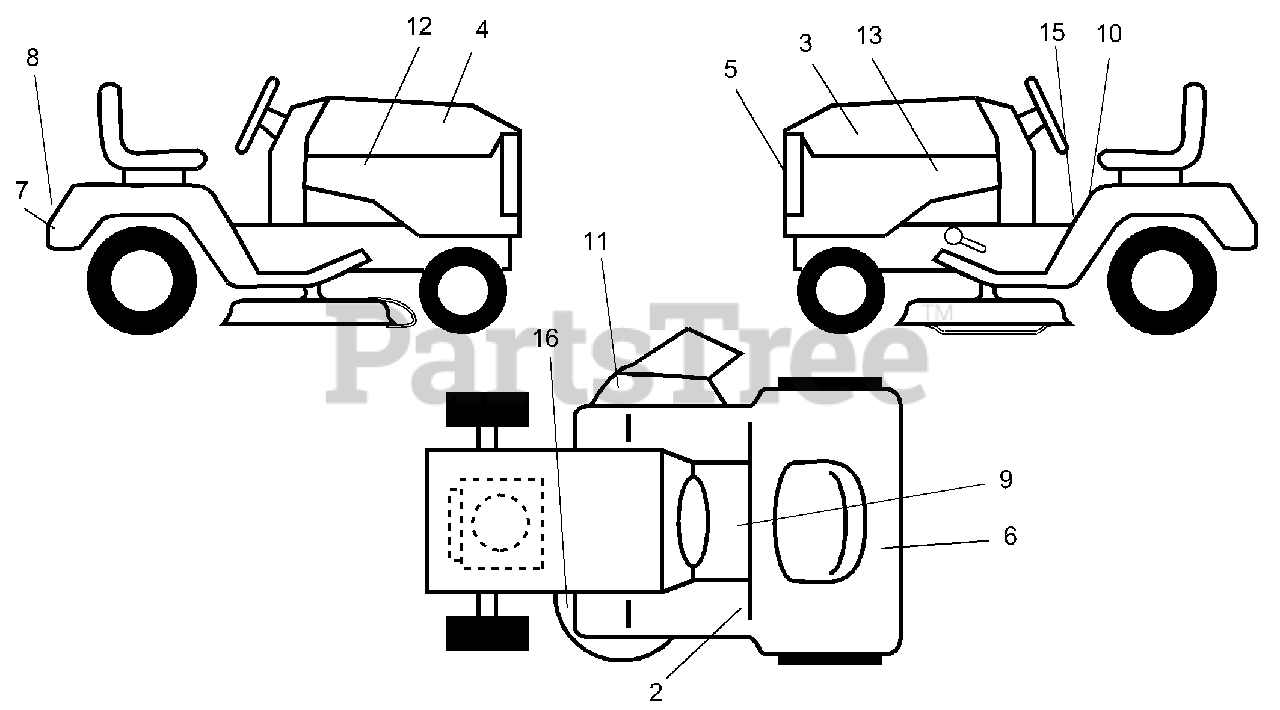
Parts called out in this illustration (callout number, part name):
2	Decal Indicator Height
3	Decal, Hood, L.H.
4	Decal, Hood, R.H.
5	Decal, Logo, Grill
6	Decal, Caution Battery
7	Decal, Drawbar
8	Decal, Logo, Fender
9	Decal, Cold Start
10	Decal, Fender, Caution
11	Decal, Warning, Multi-Language
12	Decal, Hood, Insert, R.H.
13	Decal, Hood, Insert, L.H.
15	Decal, Instruction, Operating
16	Decal, V-Belt Schematic
CR38	Grass Catcher
MK380	Mulcher Kit
